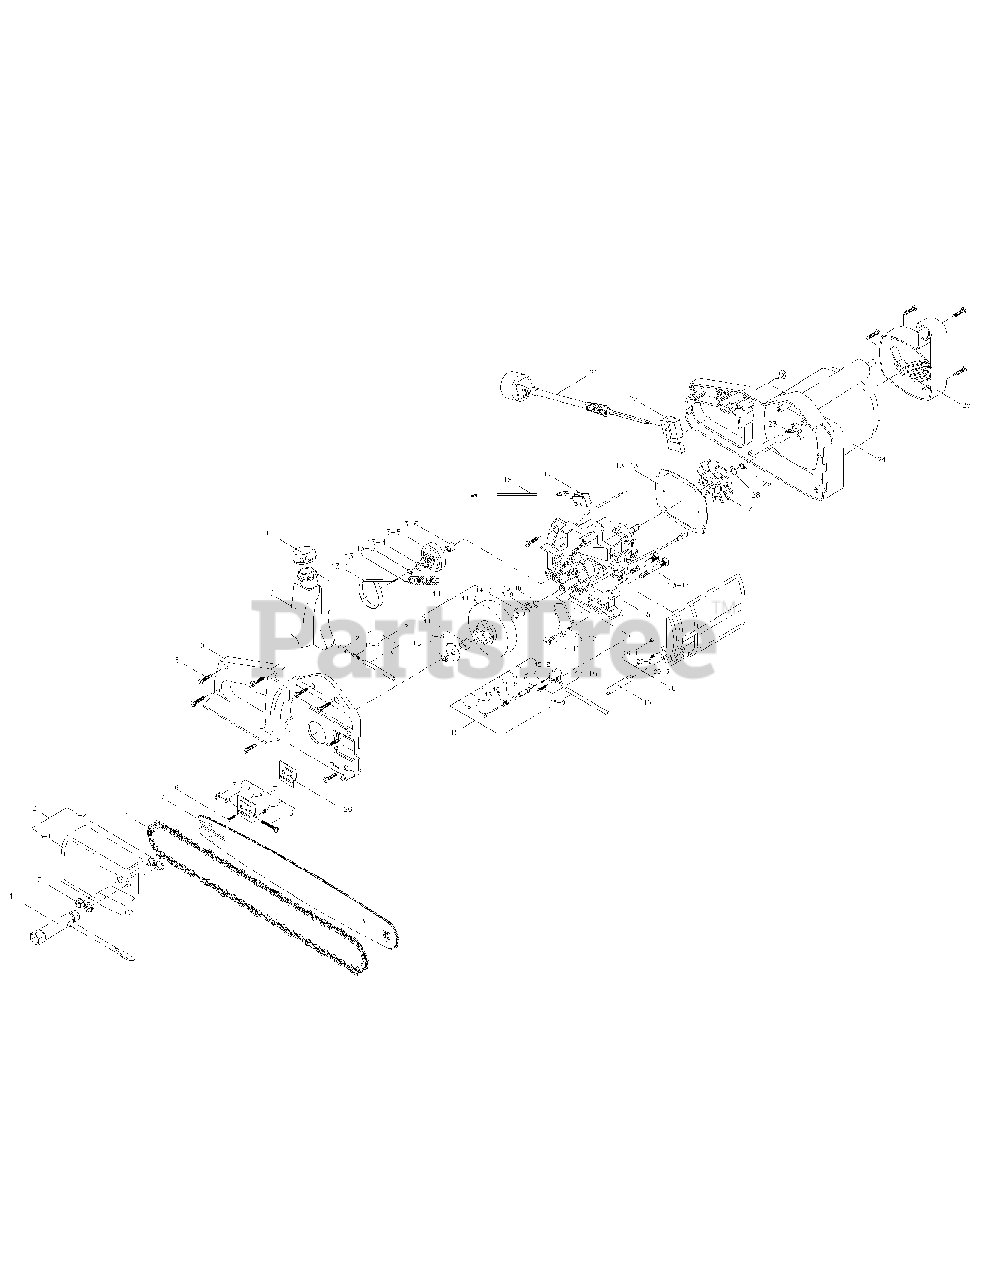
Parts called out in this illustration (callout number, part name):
3	CHAIN COVER ASS'Y
7	BAR ADJUSTMENT ASS'Y
9	HOUSING ( R )
10	LUBRICANT TANK (FOR CHAIN)
11	TANK'S COVER
12	PIPE ASS'Y
13	TRANSMISSION ASS'Y
14	INNER GEAR ASS'Y
15	LUBRICANT PUMP ASS'Y
16	CONDUIT ASS'Y
17	MICRO-SWITCH
19	BRAKE'S SHAFT
20	BRAKE'S POLE ASS'Y
21	POWER CORD TUV
22	SWITCH
23	POLE FOR BRAKE'S MICRO-SWITCH
24	HOUSING (L)
25	REAR COVER
26	OIL WASHER
